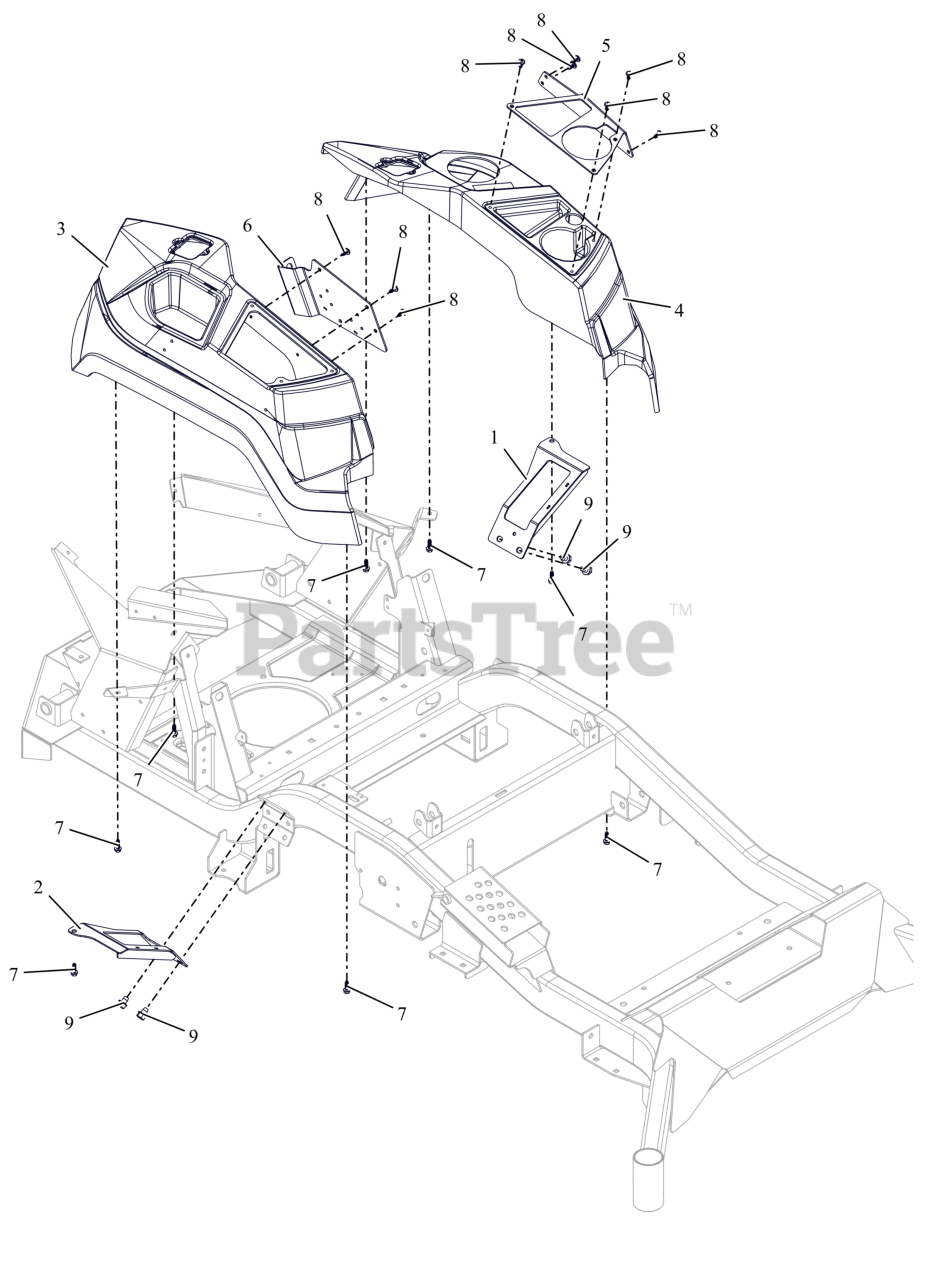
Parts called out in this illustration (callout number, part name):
1	WLDMT, LH FENDER MOUNT
2	WLDMT, RH FENDER MOUNT
3	FENDER, RH APEX - 2017
4	FENDER, LH APEX
5	PLATE, APEX CUP HOLDER COVER
6	BRKT, FENDER/RELAY MOUNTING
7	SCR, PLASTITE .25-10X.75 ZCC
8	SCR-PAN .25-15X.50 6L H/LZB500
9	SCR,TAP .375-16X.50 HWH TR ZCC
